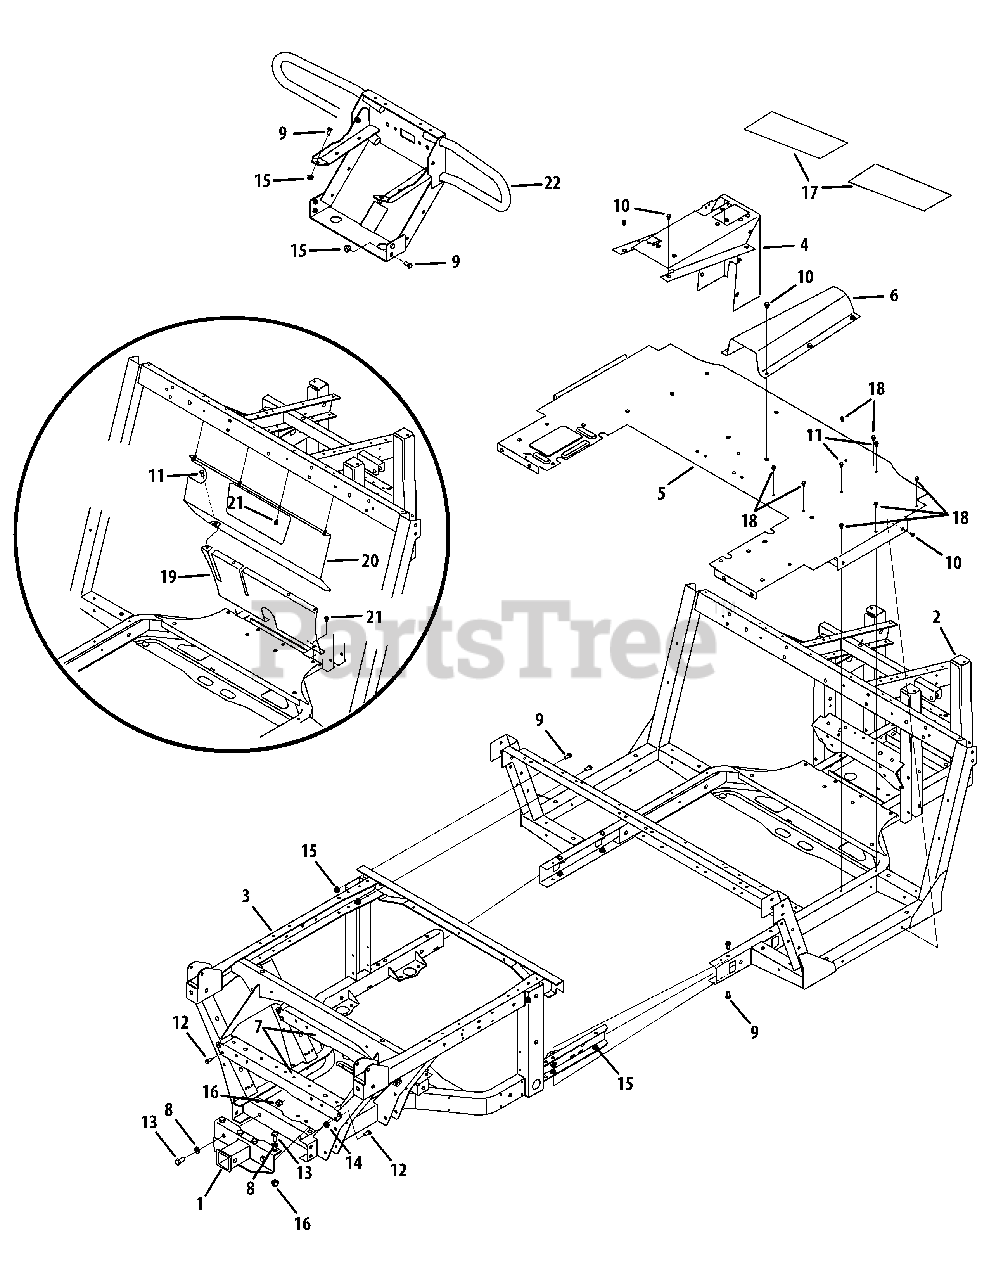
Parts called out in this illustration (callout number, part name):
2	Frm Assembly, front, uv
8	Washer, Flat, .510 x 1.00 x .060
9	Screw, 3/8-16, .75, gr5, std
10	Scr, tt, 5/16-18, 0.500, hxindwsh
11	Scr, ab, 1/4-14, 0.625, trustrxi
12	Screw, 5/16-18, .75, gr5, std
13	Screw, 1/2-13, 1.00, gr5, std
14	Nut, flglk, 5/16-18, grf, nylon
15	Nut, flglk, 3/8-16, grf, nylon
16	Nut, hexlk, 1/2-13, grb, nylon
17	Pad, abrasive, toe Plate
18	Clip, pnl, ret,
21	Scr, tt, 1/4-20 x .500
